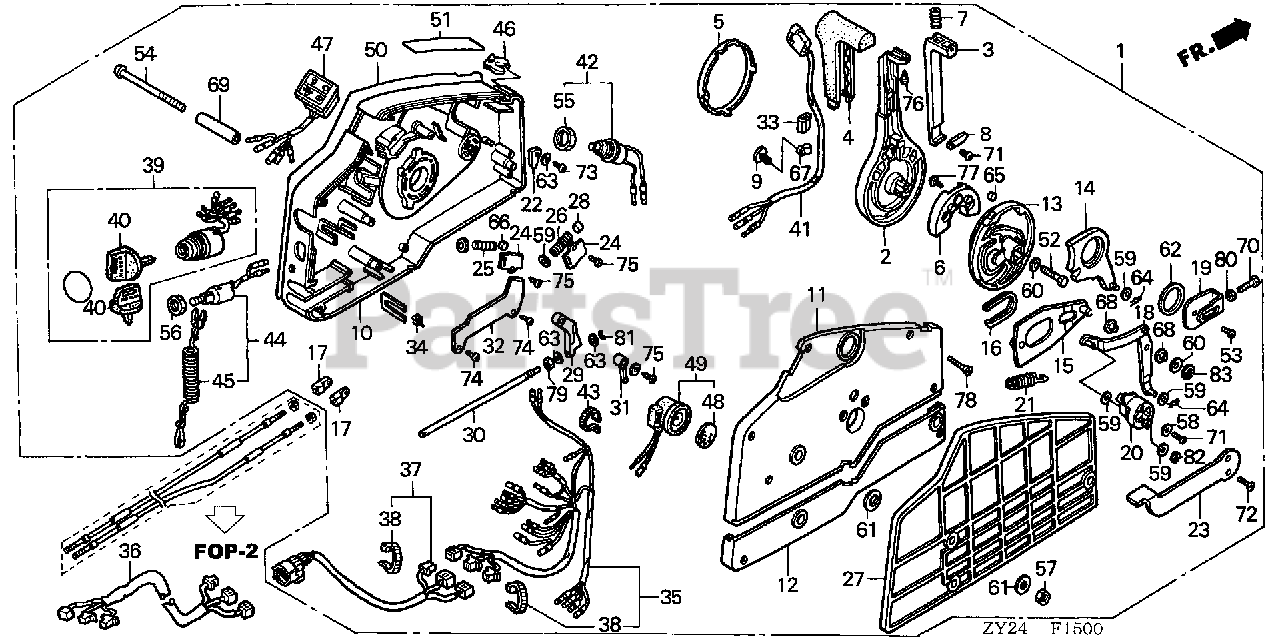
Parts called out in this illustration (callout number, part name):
1	S/R SW 2 LIGH POW TL
1	BOX ASSY., REMOTE CONTROL (P/T)
1	BOX ASSY., REMOTE CONTROL (P/T)(HI-LEX)
2	HANDLE, REMOTE CONTROL
3	LEVER, HANDLE LOCK
4	GRIP, REMOTE CONTROL HANDLE
5	CAP, HANDLE
6	BLOCK, NEUTRAL LOCK
7	SPRING, REMOTE CONTROL HANDLE
8	PLATE, LEVER SETTING
9	CLAMP, HARNESS
10	HOUSING, REMOTE CONTROL BOX (A)
11	HOUSING, REMOTE CONTROL BOX (B)
12	HOUSING, REMOTE CONTROL BOX (C)
13	WHEEL, CONTROL
14	ARM, SHIFT LINK
15	PLATE, SLIDING
16	COLLAR, SLIDING PLATE
17	PIVOT, SHIFT
18	ARM, LINK JOINT
19	BRACKET, LINK JOINT
20	WHEEL, ACCELERATOR
21	SPRING, ACCELERATOR WHEEL
22	CAM, STARTER SWITCH
23	LEVER, IDLE
24	PLATE, SPRING SETTING
25	SPRING, SHIFT CLICK
26	SPRING, CHOKE RETURN
27	SPACER, REMOTE CONTROL BOX
28	SPACER, CLICK SPRING
29	BLOCK, THROTTLE FRICTION
30	BOLT, FRICTION
31	SPACER, NEUTRAL SWITCH
32	CLAMP, POWER TILT CORD
33	PIPE, HARNESS GUIDE
34	SPACER, CABLE CLAMP
35	CABLE ASSY., REMOTE CONTROL (B)
36	CABLE ASSY., REMOTE CONTROL EXTENSION
37	CABLE ASSY., SWITCH PANEL
38	TIE, CABLE (2.4X92) (NATURAL)
39	SWITCH ASSY., COMBINATION
40	KEY ASSY., COMBINATION SWITCH (35100-ZV5-003 ONLY)
41	SWITCH ASSY., POWER TRIM-TILT
42	SWITCH ASSY., SOLENOID
43	BAND (BLACK 3.5X140)
44	SWITCH ASSY., EMERGENCY STOP
45	WIRE, EMERGENCY
46	CLIP, EMERGENCY LOCK
47	LAMP ASSY., INDICATION (2-LED)
48	PLATE, TURN SIGNAL BUZZER
49	BUZZER, WARNING
50	PLATE, REMOTE CONTROL (CAUTION PICT=SILVER)
51	MARK, FAST IDLE
52	BOLT, HEX. (8X35)
53	SCREW, PAN (6X10)
54	SCREW (6X95)
55	NUT, HEX. (20MM)
56	NUT, HEX. (16MM)
57	NUT, HEX. (6MM)
58	WASHER, PLAIN (5MM)
59	WASHER, PLAIN (6MM)
60	WASHER, PLAIN (8MM)
61	WASHER (6MM)
62	WASHER (28MM)
63	WASHER, PLAIN (4MM)
64	PIN, LOCK (6MM)
65	PIN (6X6)
66	ROLLER, CLICK
67	CLIP, WIRE HARNESS (6.3MM)
68	COLLAR, LINK JOINT
69	COLLAR, DISTANCE (6X10X43.5)
70	BOLT, HEX. (5X16)
71	SCREW, PAN (5X10)
72	SCREW, OVAL (5X12)
73	SCREW, TAPPING (4X10)
74	SCREW, TAPPING (5X8)
75	SCREW, TAPPING (5X10)
76	SCREW, TAPPING (5X12)
77	SCREW, TAPPING (6X16)
78	SCREW, TAPPING (5X25)
79	NUT, HEX. (6MM)
80	NUT, HEX. (5MM)
81	E-RING (3MM)
82	E-RING (4MM)
83	E-RING (7MM)
